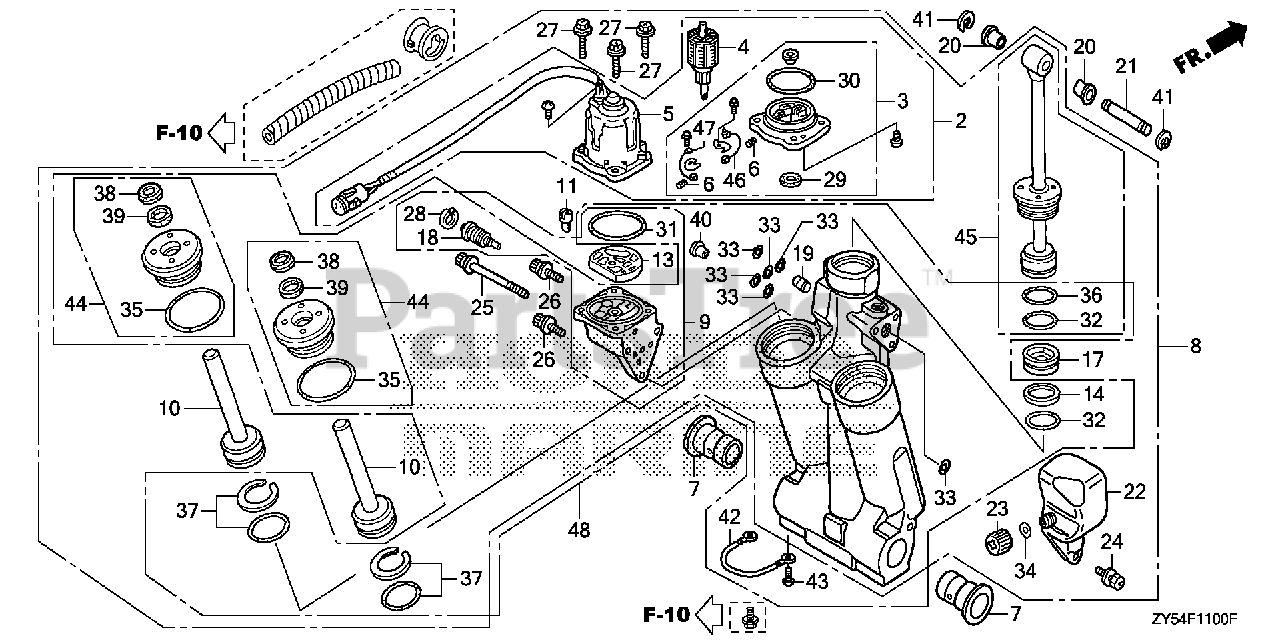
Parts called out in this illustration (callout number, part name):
2	MOTOR ASSY., POWER TILT
3	BRACKET ASSY.
5	YOKE ASSY.
6	SPRING, MOTOR
7	BUSH, SWIVEL CASE
8	TRIM-TILT ASSY., POWER
9	PUMP ASSY.
10	ROD, PISTON (B)
11	JOINT, DRIVE
13	FILTER (B)
14	RING, BACK-UP
17	PISTON, FREE
18	VALVE, MANUAL
19	VALVE, RESERVOIR
20	BUSH, CYLINDER (LOWER)
21	PIN, CYLINDER (UPPER)
22	TANK, OIL
23	CAP, OIL TANK
24	BOLT, RECESSED
25	BOLT A, SOCKET
26	BOLT B, SOCKET
27	BOLT, HEX.
28	CIRCLIP (INNER)
30	O-RING (2.0X70.5)
31	O-RING (1.8X69.6)
32	O-RING (3.5X38.7)
33	O-RING (1.8X7.7)
34	O-RING (1.9X11)
35	O-RING (3.5X35.7)
36	O-RING (3.5X41.7)
37	O-RING SET (3.5X31.7)
38	SEAL, WATER
40	COLLAR, ORIFICE
41	E-RING (15MM)
42	WIRE, LEAD (1.5X116MM)
43	SCREW, PAN (6X8)
44	GUIDE, ROD
45	ROD, PISTON
46	BREAKER ASSY.
47	BRUSH ASSY.
